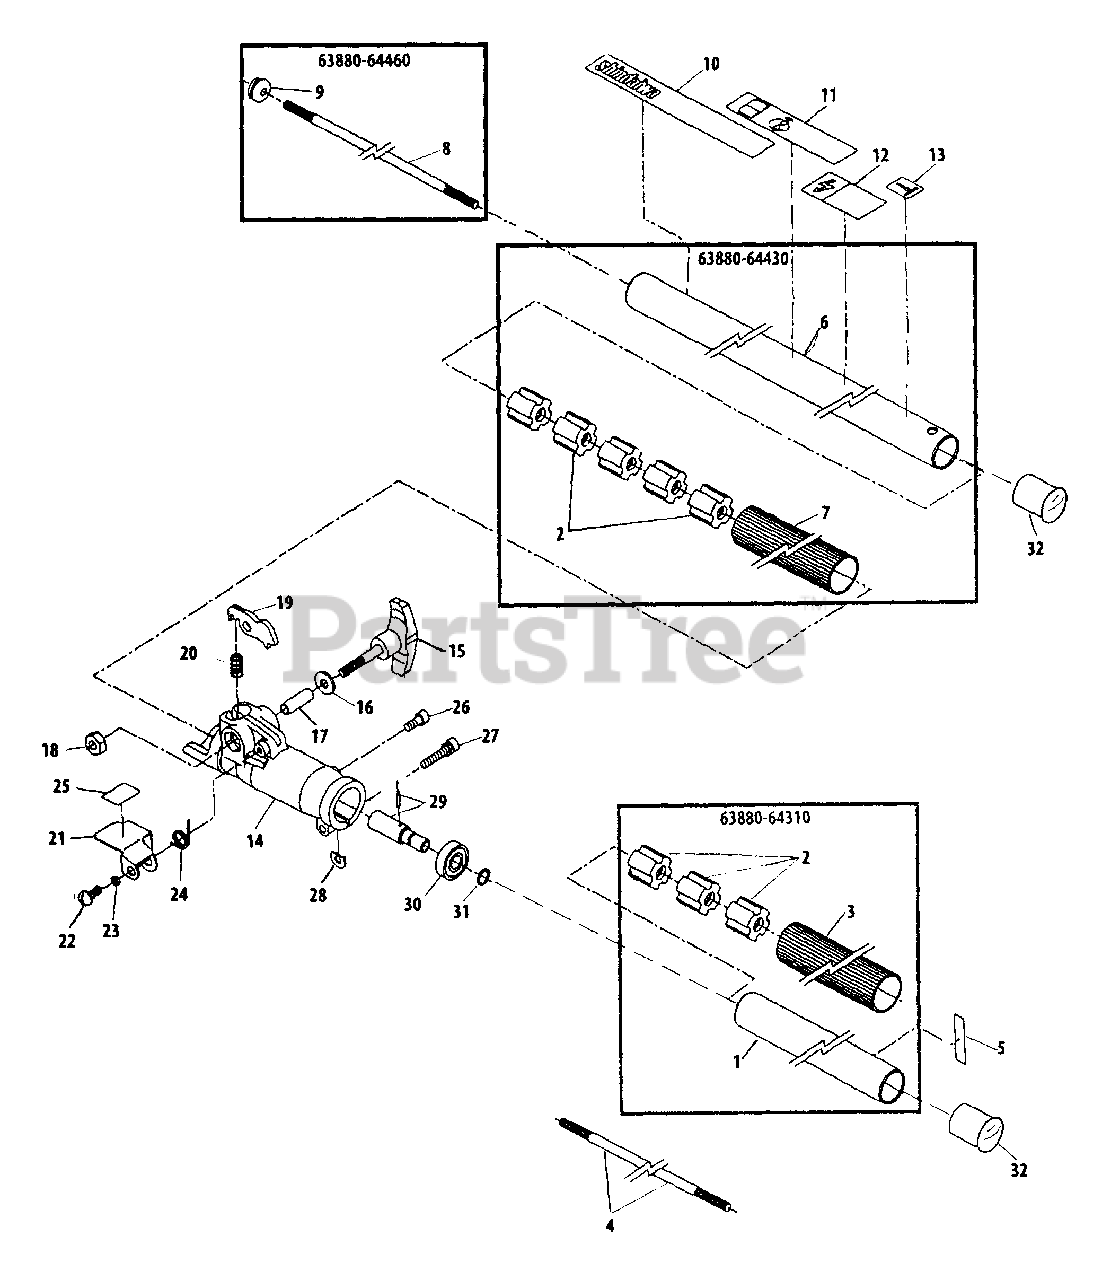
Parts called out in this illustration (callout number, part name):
1	PIPE, MAIN
2	BUSHING
4	PIPE, MAIN
5	LABEL - HANDLE LOCATION
6	PIPE, MAIN
7	GRIP
8	PIPE, MAIN
9	GROMMET
10	LABEL - MODEL
11	LABEL - CAUTION
12	LABEL - CAUTION
13	LABEL - ALIGNMENT
14	COUPLER
15	KNOB
16	WASHER
17	COLLAR
18	NUT
19	LEVER, LOCK
20	SPRING
21	COVER
22	SCREW
23	COLLAR
24	SPRING
25	LABEL - LATCH INSTRUCTION
26	SCREW - 5X12
27	SCREW - 5X25
28	SHIM
29	CONNECTOR, SHAFT
30	BEARING, BALL - 609ZZ
31	RING, RETAINING
32	CAP
63880-64310	MAIN PIPE ASSY
63880-64430	MAIN PIPE ASSY
63880-64460	DRIVESHAFT ASSY
